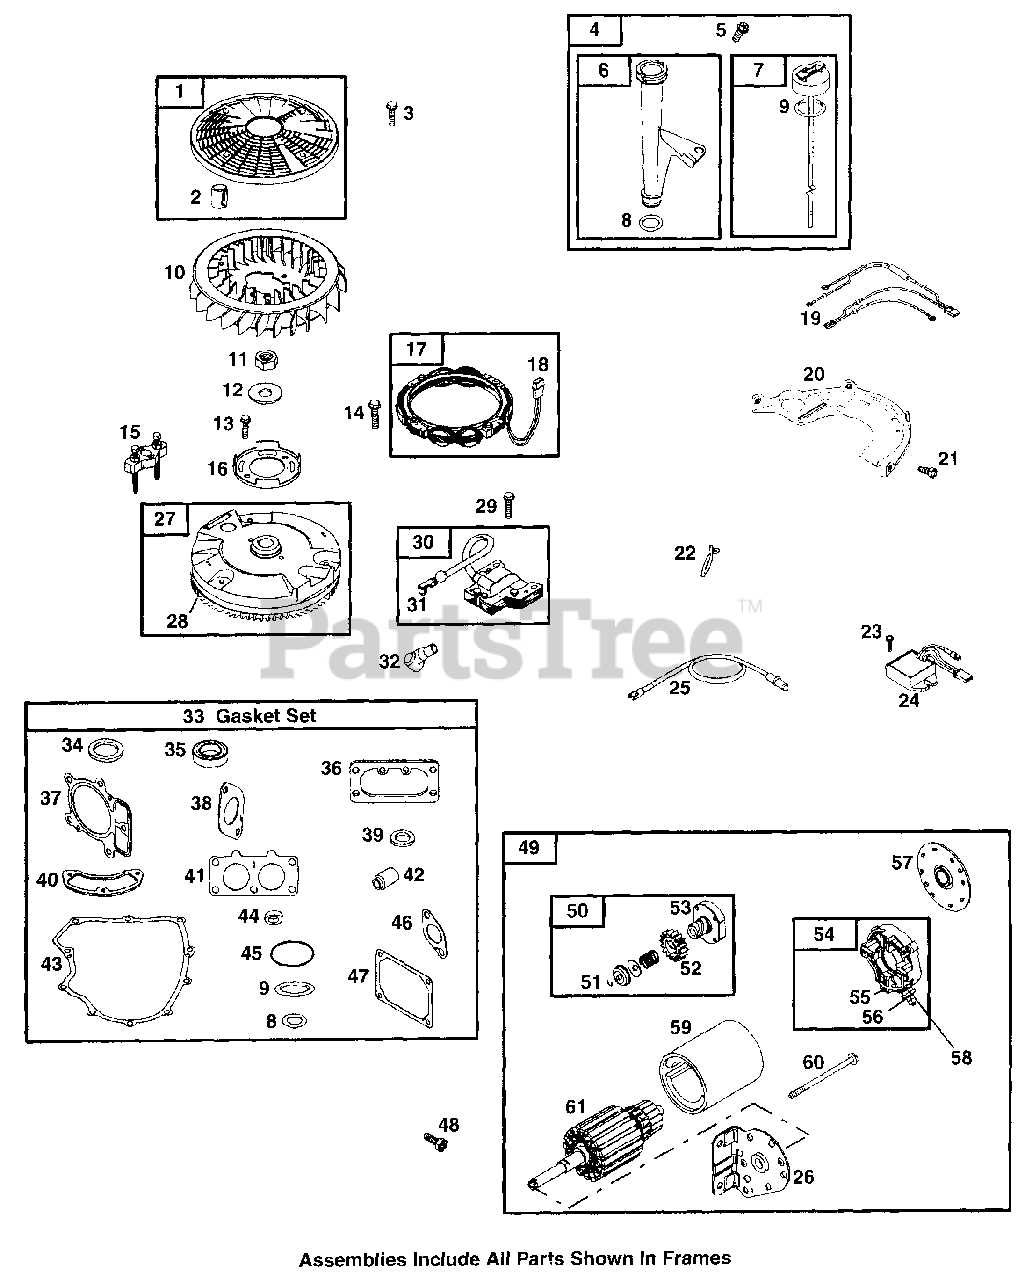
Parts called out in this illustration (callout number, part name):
1	Rotating Screen
3	Screw (Rotating Screen)
4	Dipstick/Tube Assembly
5	Screw (Dipstick Tube)
6	Dipstick Tube
7	Dipstick
8	Dipstick Tube Seal
9	Dipstick/Tube Seal
10	Flywheel Fan
11	Nut (Flywheel)
12	Washer (Flywheel)
13	Screw (Fan-Retainer)
14	Screw (Alternator)
15	Flywheel Puller
16	Fan Retainer
17	Alternator (Dual Circuit)
18	Alternator Connector/Wire
19	Wiring Harness
20	Back Plate
21	Screw (Back Plate)
23	Screw (Regulator)
24	Regulator (Regulated-16 Amp)
25	Wire Assembly
27	Flywheel
29	Screw (Magneto Armature)
30	Magneto Armature
31	Sparkplug Terminal
32	Sparkplug Boot
33	Engine Gasket Set
34	Oil Seal (Magneto Side)
35	Oil Seal (PTO Side)
36	Air Cleaner Gasket
37	Cylinder Head Gasket
38	Intake Gasket
39	Sealing Washer
40	Breather Gasket
41	Intake Gasket
42	Valve Seal
43	Crankcase Gasket
44	Governor Shaft Seal
45	O-Ring Seal (Oil Pump Cover)
46	Exhaust Gasket
47	Rocker Cover Gasket
48	Screw (Drive Cap)
49	Starter Motor
50	Starter Drive
51	Retaining Ring
52	Pinion Gear
53	Drive Clutch
54	Brush Retainer
56	Nut (Brush Retainer)
58	Nut (Brush Retainer)
59	Housing-Starter
60	Bolt (Starter Motor)
61	Armature (Serviced By Starter Only)
